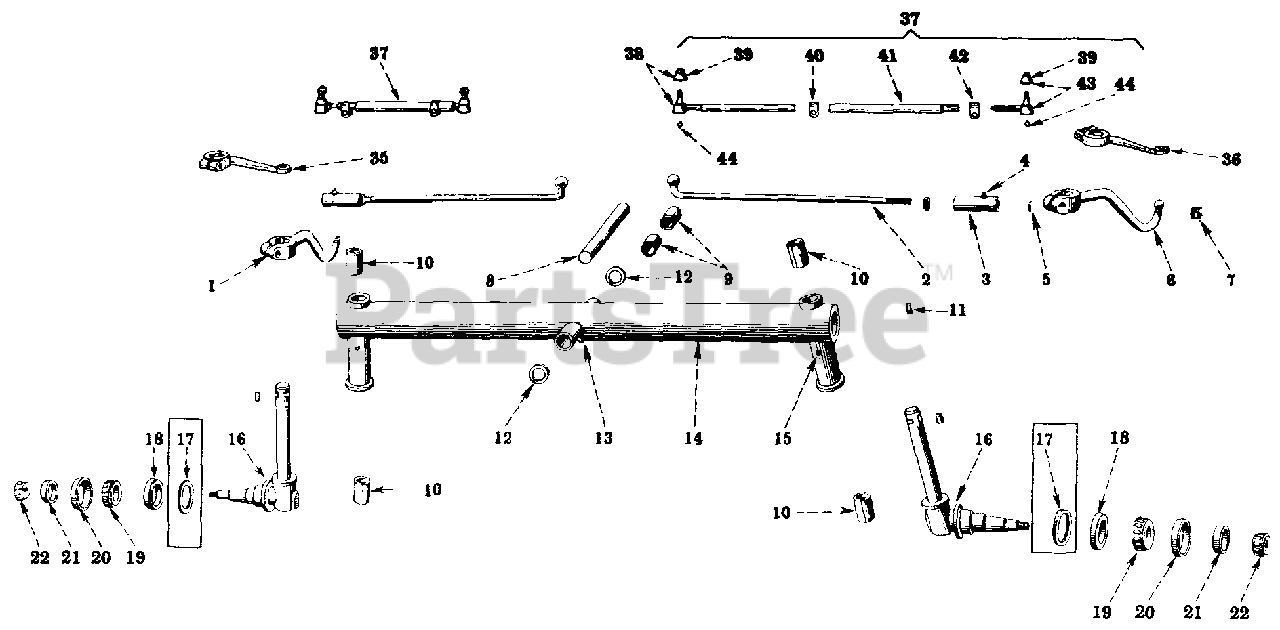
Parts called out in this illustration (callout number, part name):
1	ARM, STEERING KNUCKLE LH
2	TIE ROD ASSY 17-9/32 IN. LONG
2	TIE ROD ASSY 18-7/16 IN. LONG
3	END, TIE ROD ADJUSTABLE
4	FITTING, 1/4-28 NS TAPER STR LUB
5	SEAT TIE ROD BALL
6	ARM, STEERING KNUCKLE RH
7	SEAT, TIE ROD ADJUSTABLE BAIL
8	SHAFT, FRONT AXLE PIVOT
9	BUSHING, FRONT AXLE PIVOT
10	BUSHING, STEERING KNUCKLE POST TUBE
11	KEY, .25 X .88 SQ. PARALLEL
12	WASHER, FRONT AXLE PIVOT THRUST
13	FITTING, 1/4-28 NS TAPER STR LUB
14	AXLE, FRONT
15	FITTING, 1/4-28 NS TAPER STR LUB STEERING KNUCKLE POST
16	KNUCKLE, STEERING LH
16	KNUCKLE, STEERING RH
17	WASHER, FRONT WHEEL FELT
18	SEAL, FRONT WHEEL OIL
19	BEARING ASSY, FRONT WHEEL INNER CONE
20	BEARING, FRONT WHEEL INNER CUP
21	BEARING, FRONT WHEEL OUTER CUP
22	BEARING ASSY, FRONT WHEEL OUTER CONE
35	ARM, STEERING KNUCKLE LH
36	ARM, STEERING KNUCKLE RH
37	TIE ROD ASSY
38	END ASSY, TIE ROD
39	COVER, TIE ROD END DUST
40	CLAMP, TIE ROD
41	TUBE, TIE ROD
42	CLAMP, TIE ROD
43	END ASSY, TIE ROD
44	FITTING, 1/4-28 NS TAPER STR LUB
